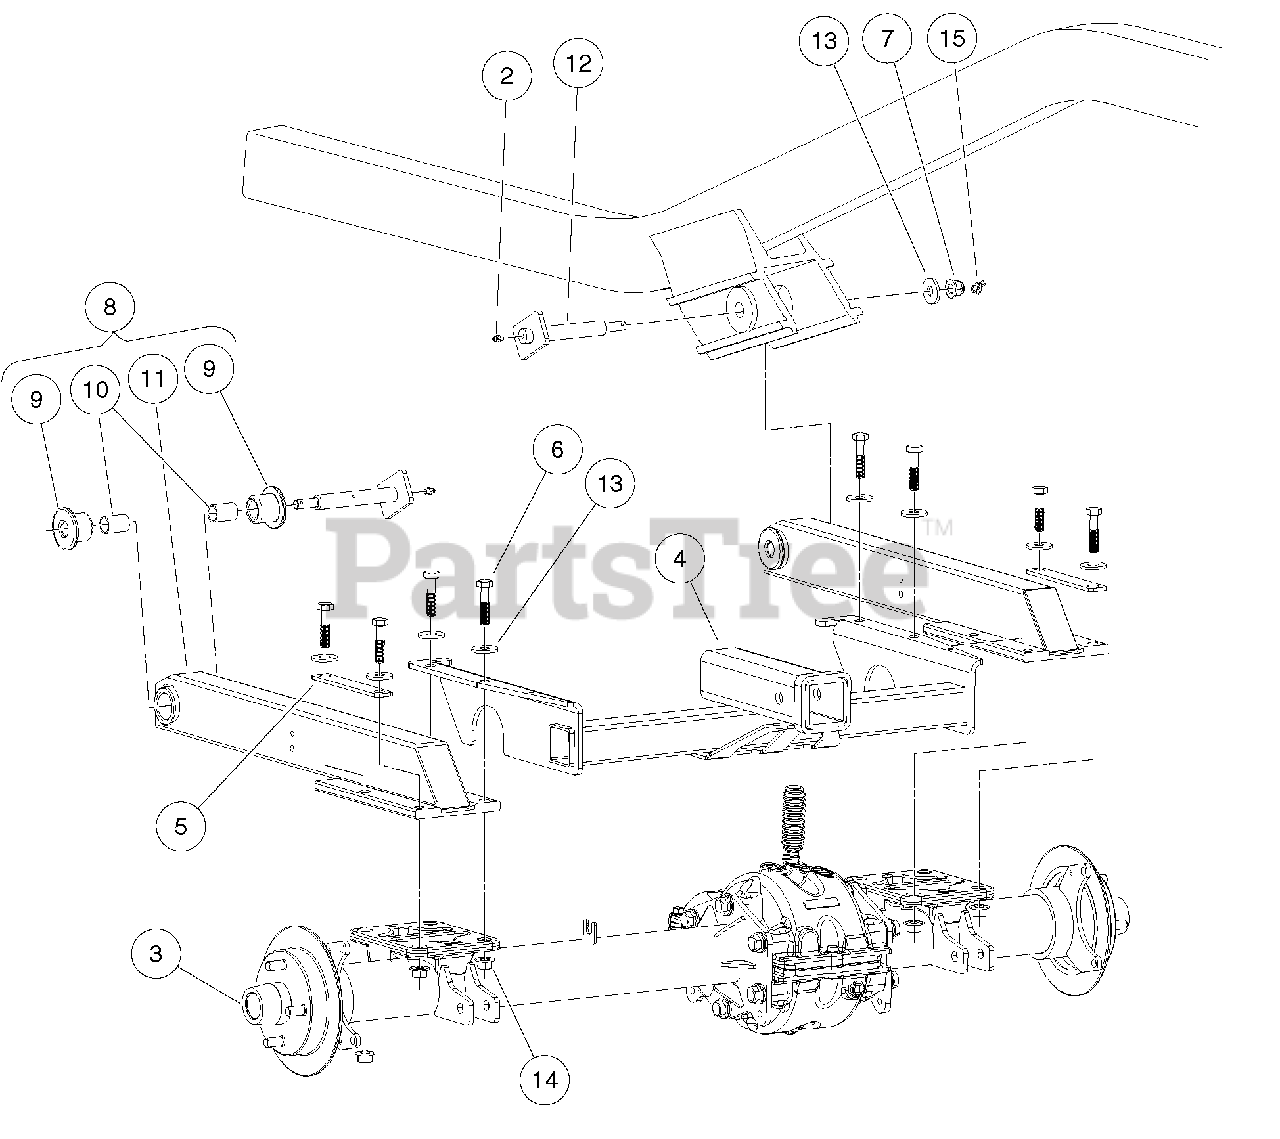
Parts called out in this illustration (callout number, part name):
1	Instl, Rear Suspension
2	Fitting, 1/4-28 Thread-Forming Grease
3	Center Cap, Rubber
4	Weldment, Receiver, Rear
5	Washer, Strip, Swingarm
6	Bolt Flanged Head, M12 X 1.75 X 50
7	Nut Flg, M12x1.75, Nylon Gr 10
8	Sub Asm Swingarm
9	Bushing, Pivot, Urethane
10	Bushing, Teflon
11	Swingarm, Rear, Awd
12	Pin, Swingarm, Weldment
13	Washer, M12 Hard Regular
14	Nut Flg M12 X 1.75 Cl10
15	Cotter, Rue Ring, 1/2"
